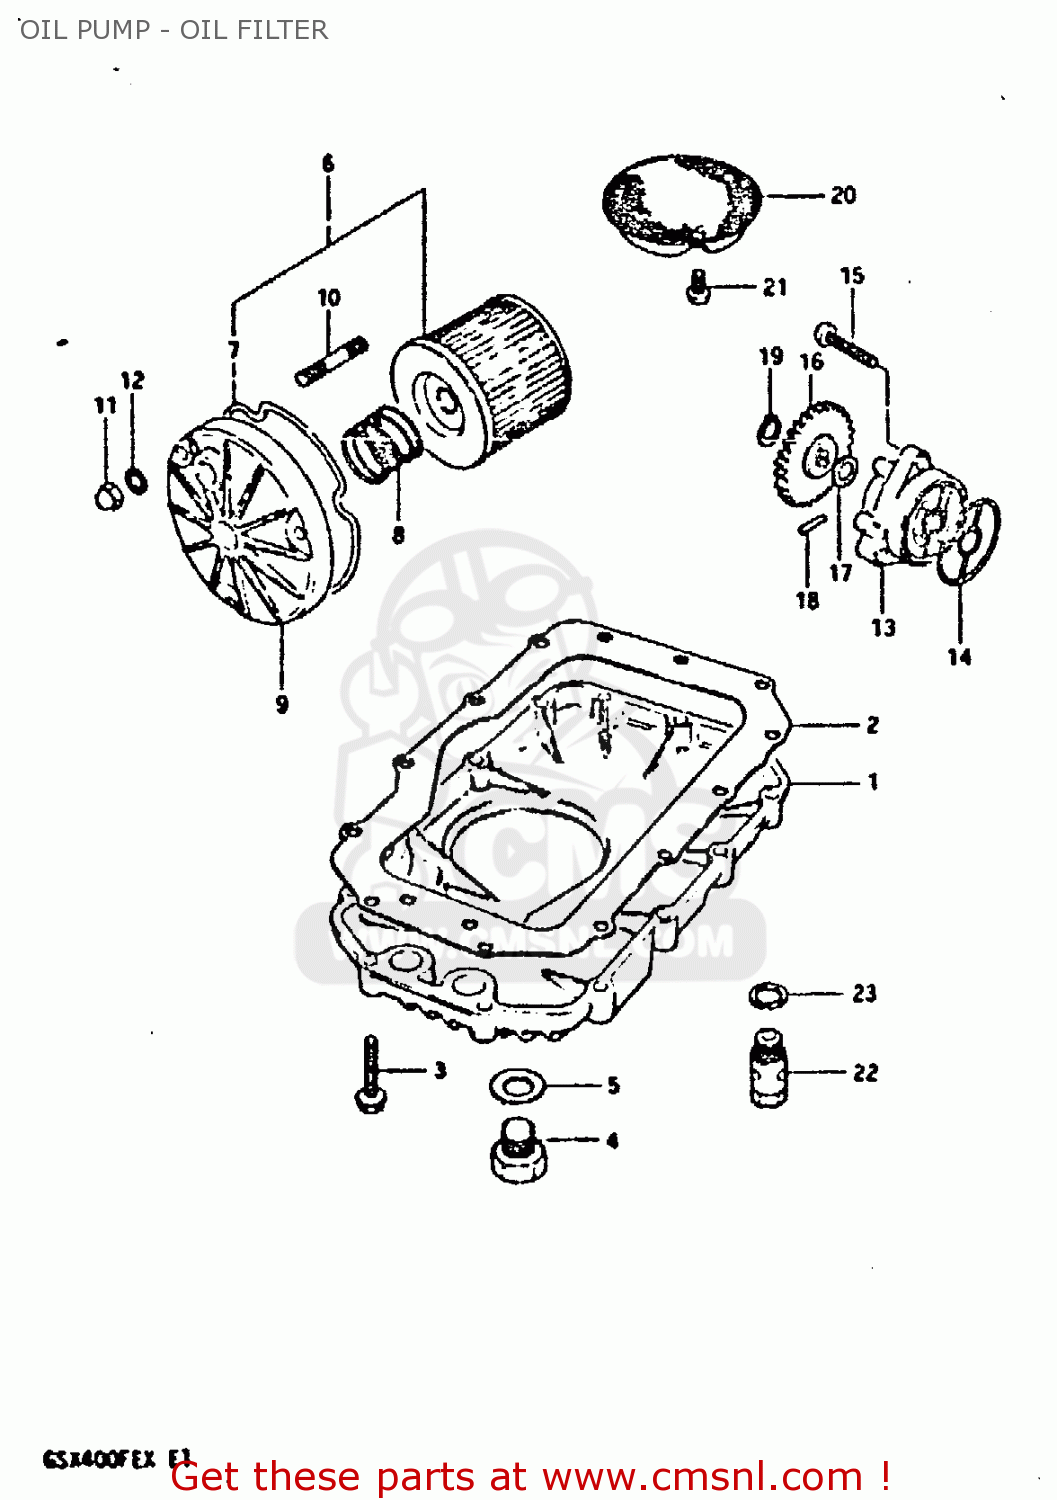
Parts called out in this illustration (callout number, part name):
1	PAN, OIL
2	GASKET
3	BOLT
4	PLUG
5	GASKET(14X19.2X2) (NAS)
6	ENGINE OIL FILTER SET
7	O RING,OIL FILTER CHAMBER CAP
8	SPRING
9	CAP,OIL FILTER
10	STUD 6X20
11	NUT
12	WASHER
13	PUMP ASSEMBLY,OIL
14	O-RING,OIL PUMP
15	SCREW
16	GEAR,ENG OIL PUMP DRIVEN
17	SHIM
18	PIN(4X15.8)
19	CIRCLIP
20	STRAINER,ENGINE OIL
21	SCREW 6X12
22	REGULATOR ASSEMBLY,ENGINE
23	WASHER
